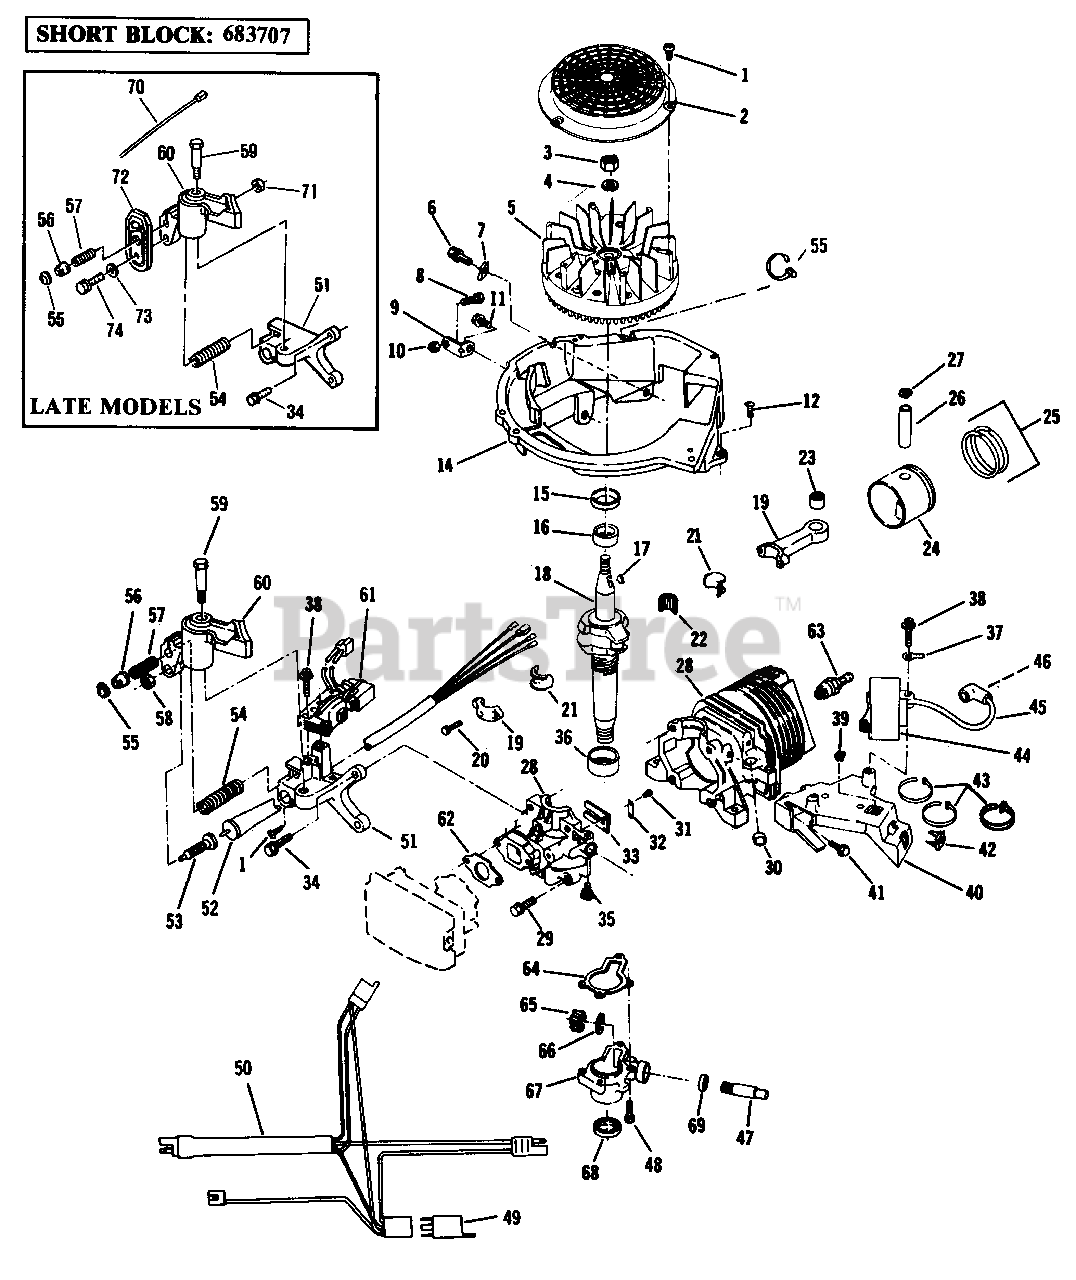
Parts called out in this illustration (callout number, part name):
1	Screw-Flywheel Screen and Switch
2	Screen-Flywheel
3	Nut-Flywheel
4	Lockwasher
5	Flywheel
6	Screw
7	"J"Clip
8	Bolt-Brace-Alt. Brk't.
9	Brace-Alt. Bracket
10	Locknut-Brace-Alt. Brk't.
11	Screw
12	Screw-Shd. Base to C.D. Brk't.
13	Tie Rap
14	Base-Shroud
15	Oil Seal-Upper
16	Bearing-Upper
17	Key-Flywheel
18	Crankshaft
19	Connecting Rod Assembly
20	Screw-Cap
21	Liner Split
22	Needle Bearing Set
23	Bearing Assembly
24	Piston and Ring Set
25	Ring Set
26	Wrist Pin
27	Retaining Ring
28	Cylinder and Crankcase Cover Assembly
29	Screw-Cover to Crankcase
30	Plug
31	Screw-Reed to C'case Cover
32	Plate-Reed Hold Down
33	Reed
34	Screw-Alt. and Brake Mtg. Brk't.
35	Set Screw-Starter Assembly
36	Bearing-Lower
37	Terminal-Ground Lead
38	Screw-C.D. and Alt. Mtg.
38	Screw-C.D. Mtg.
39	Grommet-C.D. Bracket
40	Bracket-Ignition Mtg.
41	Screw
42	Grommet-C.D. Brk't.
43	Tie Strap
44	C.D. Ignition Module and Lead Assembly
45	High Tension Lead and Cover Assembly
46	Spring Terminal
47	Driveshaft
48	Screw-Gear Box
49	Relay
50	Wire Harness Assembly
51	Bracket-Alt. and Brake
51	Bracket-Brake
52	Brake Switch Assembly
53	Plunger
54	Spring-Brake
55	Retainer
56	Actuator-Brake Lever
57	Spring-Cable Retainer
58	Nut
59	Bolt-Shoulder
60	Brake Assembly
61	Alternator Assembly
62	Gasket-Carb. to C'case Cover
63	Spark Plug
64	Gasket-Gear Box
65	Gear
66	Washer-Thrust
67	Gear Box Assembly
68	Oil Seal Crankshaft
69	Seal-Driveshaft
70	Lead Assembly
71	Nut
72	Switch Assembly
73	Washer
74	Bolt
